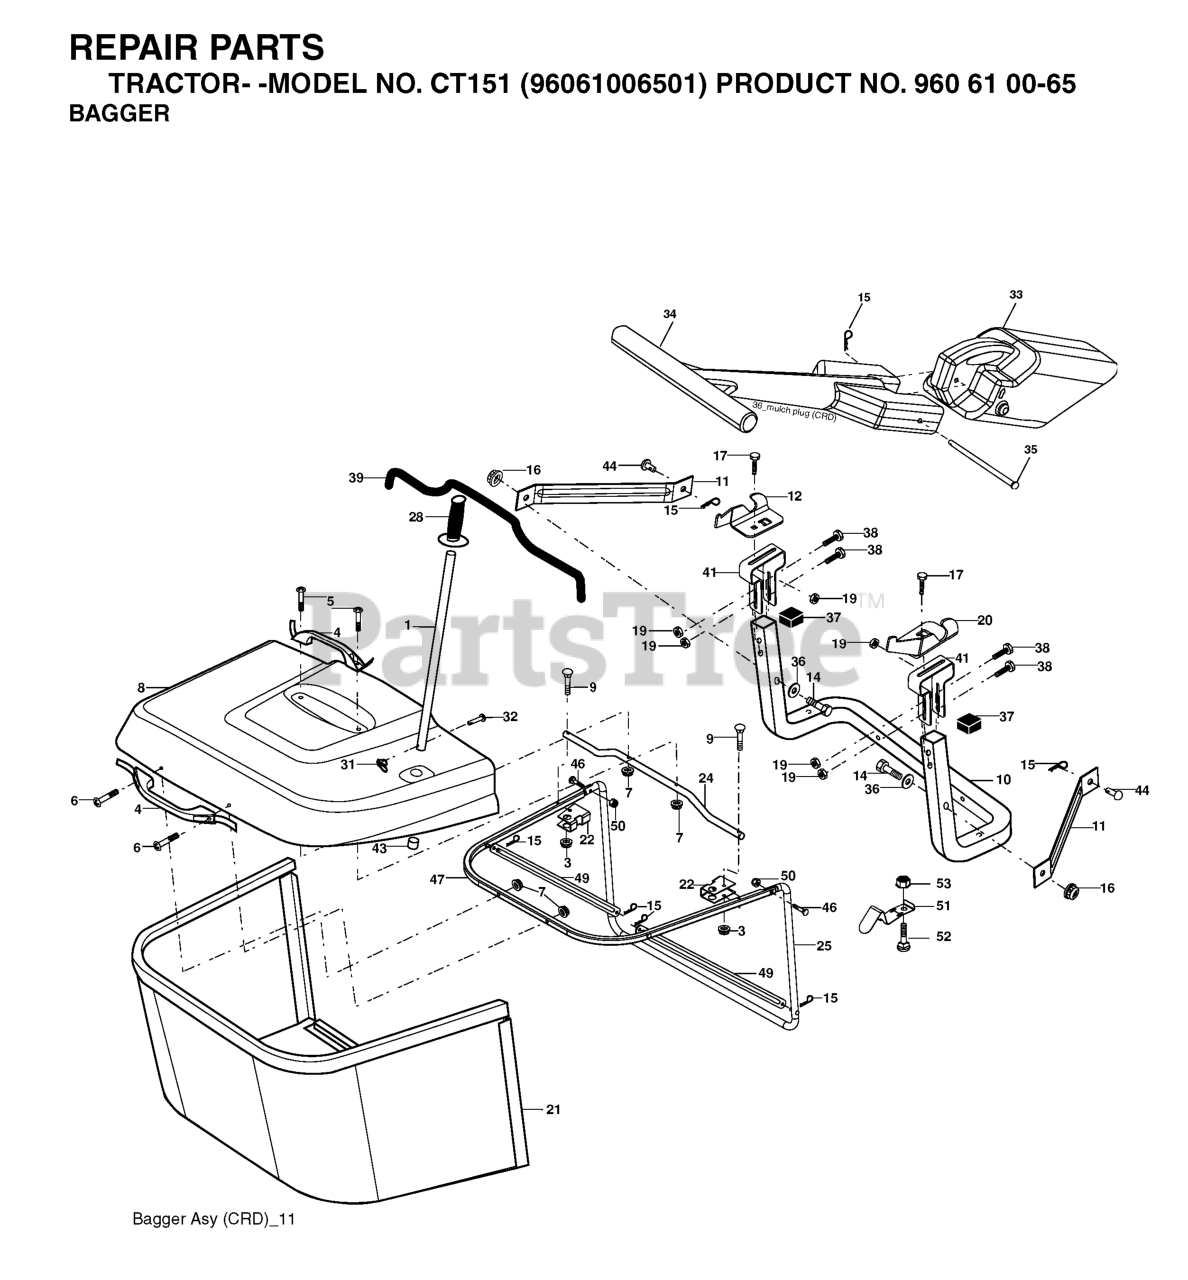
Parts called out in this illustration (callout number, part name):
1	TUBE HANDLE
3	NUT T
4	HANDLE.BAGGER.W/LVRS.BLK.CRD
5	SCREW.PAN.HEAD
6	REPL BY 532 75 00-29
8	COVER.PNT.BGR.CRD.WSLOTS.MS668
9	Bolt Carriage 1/4-20 x 2.25d x Gr.5
10	TUBE
11	BRACKET.SUPPORT.UPPER.BAG.CRD
12	BRKT PIVOT
14	BOLT-HEX EAK
15	RETAINER-SPRNG RB
16	NUT LOCK FLG 3/8-16 UNC
17	RP BOLT 5/16-18 X3/4 ZN/YEL GR
19	NUT LOCK HEX FLANGE 5/16-18
20	BRKT.PIVOT.RH.CRD
22	BRKT.SIDE.BAG.CRD
24	TUBE.PIVOT.BAG.CRD.BLACK
25	PIPE
28	GRIP.HANDLE.BLACK
31	RETAINER CLIP
32	RIVET,DRILLED
33	PLUG.MULCHER.92 CRD
34	HANDLE.MULCHER.92.CRD (2 2)
36	WASHER
37	Plug Support Bagger CRD
38	BOLT.5/16-18X2.5
39	SEAL.TRIM.37'
41	BRKT.VERT.ADJ.BAGGER.CRD
43	PLUG, TUBING END
46	BOLT.CARRIAGE.5/16-18
47	PIPE
49	ROD
50	NUT.71038.31-18.HEX.NYLOCK
51	LATCH
52	BOLT
53	NUT
